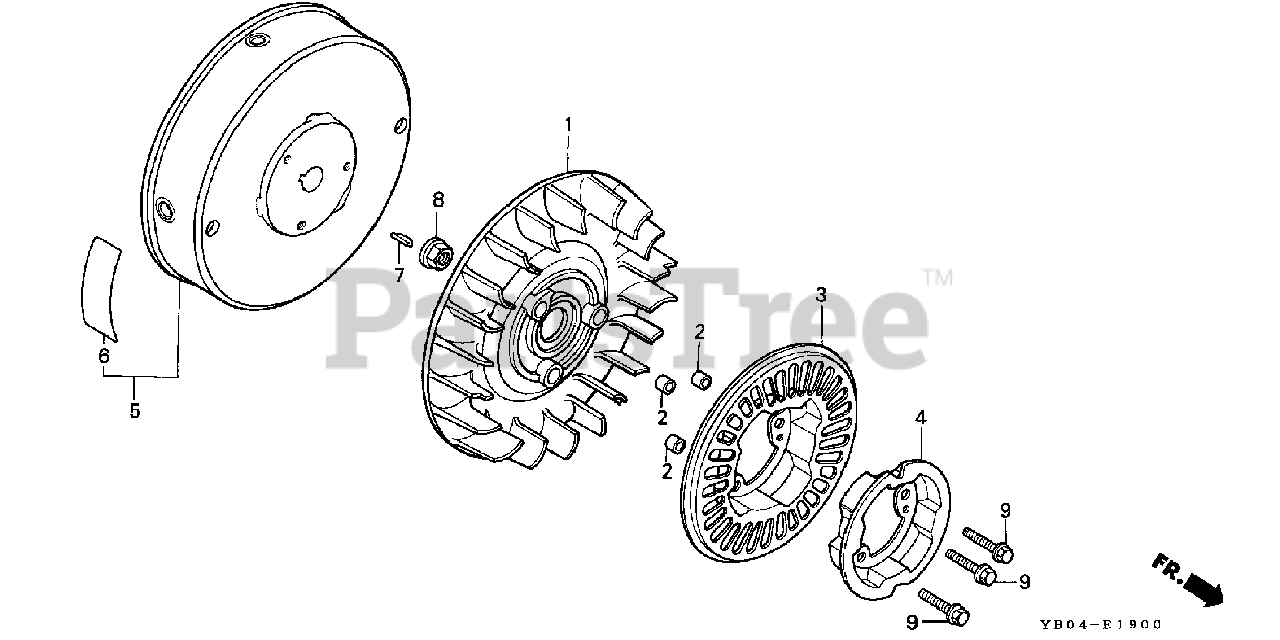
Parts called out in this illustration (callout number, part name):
1	FAN, COOLING (NOT AVAILABLE)
2	COLLAR, FAN
3	GRID, SCREEN
4	PULLEY, STARTER
6	MARK, FLYWHEEL CAUTION
7	KEY, WOODRUFF (3MM)
8	NUT, FLANGE (12MM)
9	BOLT, FLANGE (6X22)
